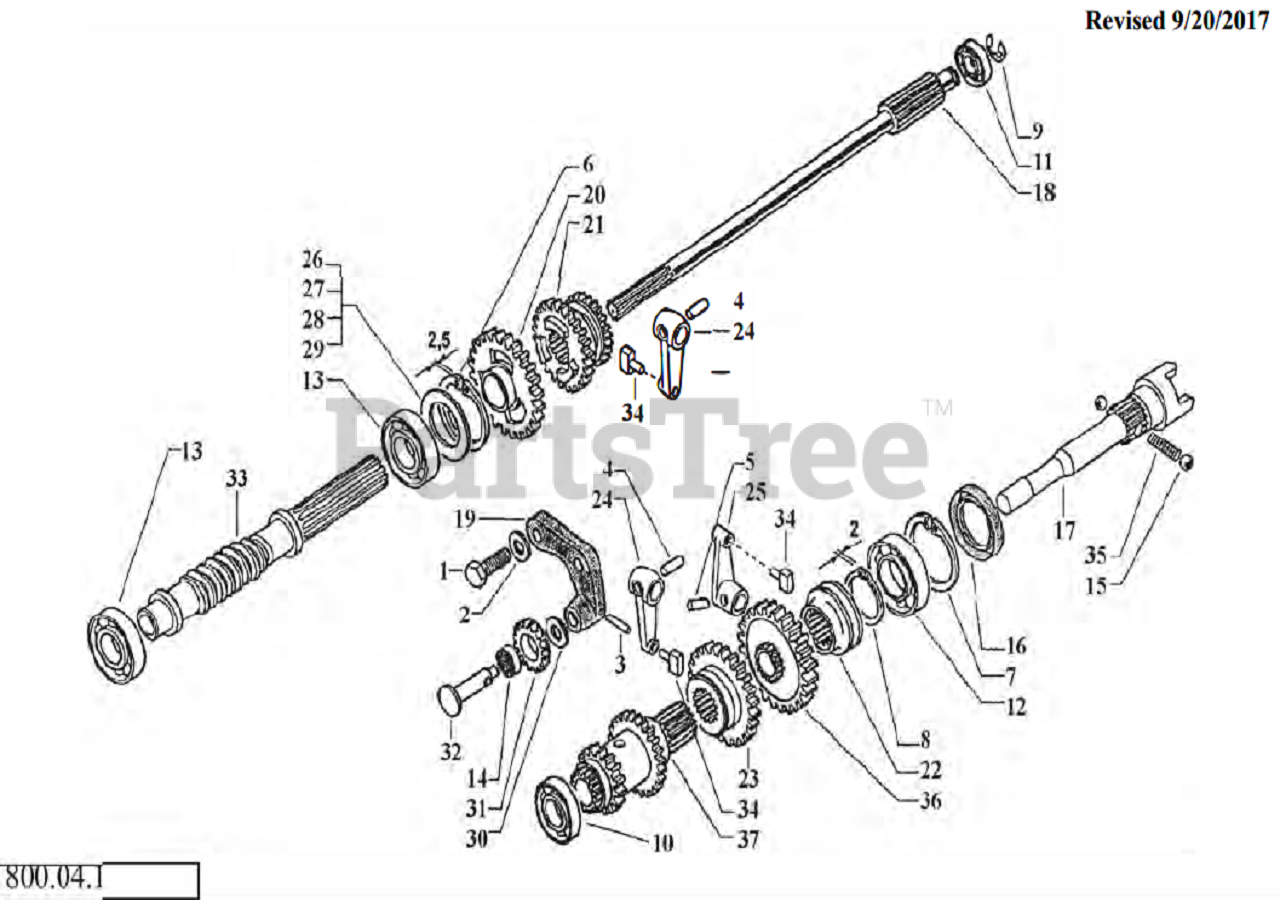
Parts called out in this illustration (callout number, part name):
1	CAP SCREW M10X30
2	WASHER, SUPER M10
3	PIN, SPLIT
4	PIN SPIRAL SPLIT
5	PIN SPIRAL SPLIT
6	SNAP RING D52
7	SNAP RING D55
8	SNAP RING D31
9	RING, SPLIT
10	BEARING 15X35X11
11	BEARING 15X42X13
12	BEARING 30X55X13
13	BEARING 25X52X15
14	BEARING 12X15X10
15	BALL 1/4"
16	OIL SEAL 38X55X7
17	SHAFT PTO
18	MAIN INPUT SHAFT
19	SUPPORT REVERSE GEAR
20	GEAR, FIRST
21	GEAR, SLIDER
22	PTO SLIDER
23	SLIDER REVERSER
24	LEVER REVERSER
25	LEVER PTO ENGAEMENT
26	SHIM 1.5 MM
27	SHIM 1.6 MM
28	SHIM 1.7 MM
29	SHIM 1.8 MM
30	WASHER
31	REVESER GEAR
32	PIN REVERSE GEAR
33	WORM GEAR
35	SPRING FOR PTO BALLS
36	GEAR PTO
37	GEAR CLUSTER
